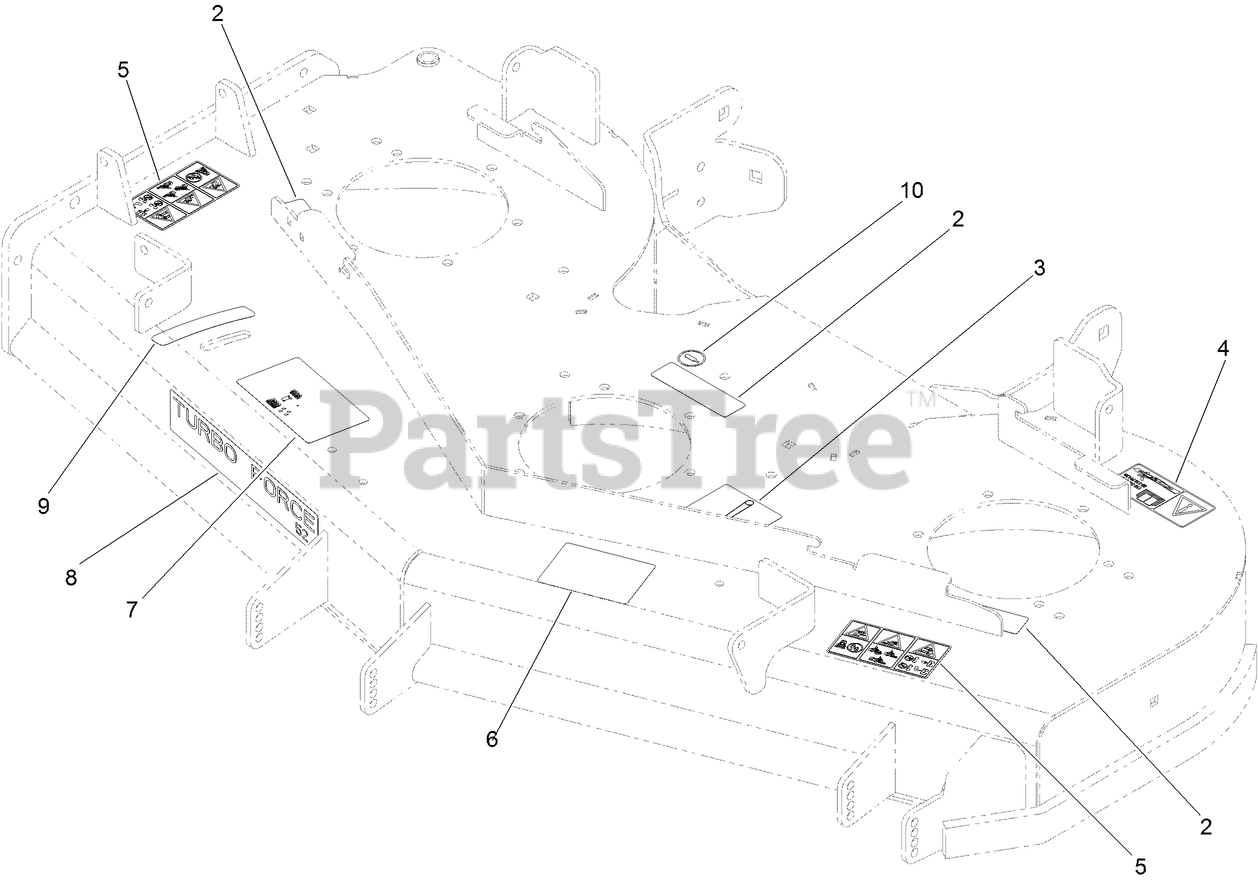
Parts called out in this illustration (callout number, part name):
2	DECAL-MISSING, COVER
3	DECAL-ROUTING, DECK BELT
4	DECAL-TORQUE, BLADE BOLT
5	DECAL-DANGER
6	DECAL-ANTI SCALP
7	DECAL-ADJUSTMENT, BAFFLE
9	DECAL-SETTING, BAFFLE
10	DECAL-GREASE
